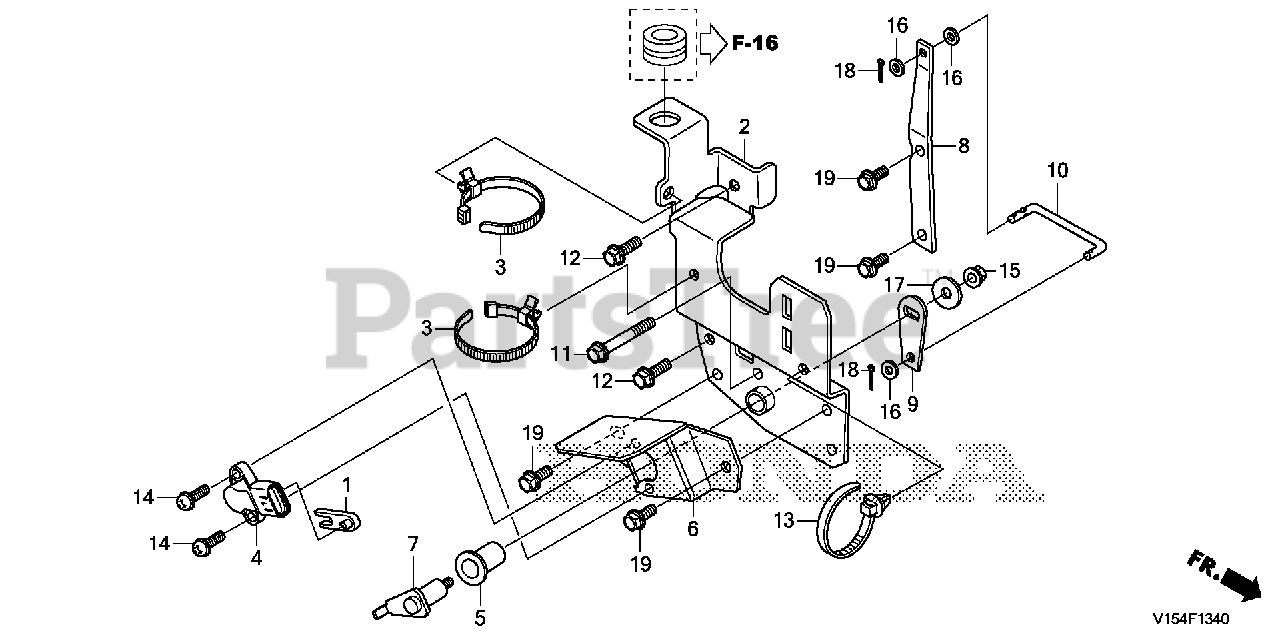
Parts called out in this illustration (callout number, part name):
1	ARM, TURN LEVER
2	BRACKET, CONNECTOR
3	BAND, WIRE HARNESS
4	SENSOR ASSY., ANGLE
5	BUSH, PARKING BRAKE
6	BRACKET, HEIGHT SENSOR
7	SHAFT, HEIGHT SENSOR
8	ARM A, HEIGHT SENSOR
9	ARM B, HEIGHT SENSOR
10	ROD, HEIGHT SENSOR
11	BOLT, FLANGE (6X40) (CT200)
12	BOLT, FLANGE (6X14) (CT200)
13	CLIP, HARNESS BAND (145MM) (BLACK)
14	SCREW-WASHER (5X18) (NOT AVAILABLE)
15	NUT, FLANGE (6MM)
16	WASHER, PLAIN (5MM)
17	WASHER, PLAIN (6MM)
18	PIN, SPLIT (1.6X12)
19	BOLT, FLANGE (6X12)
